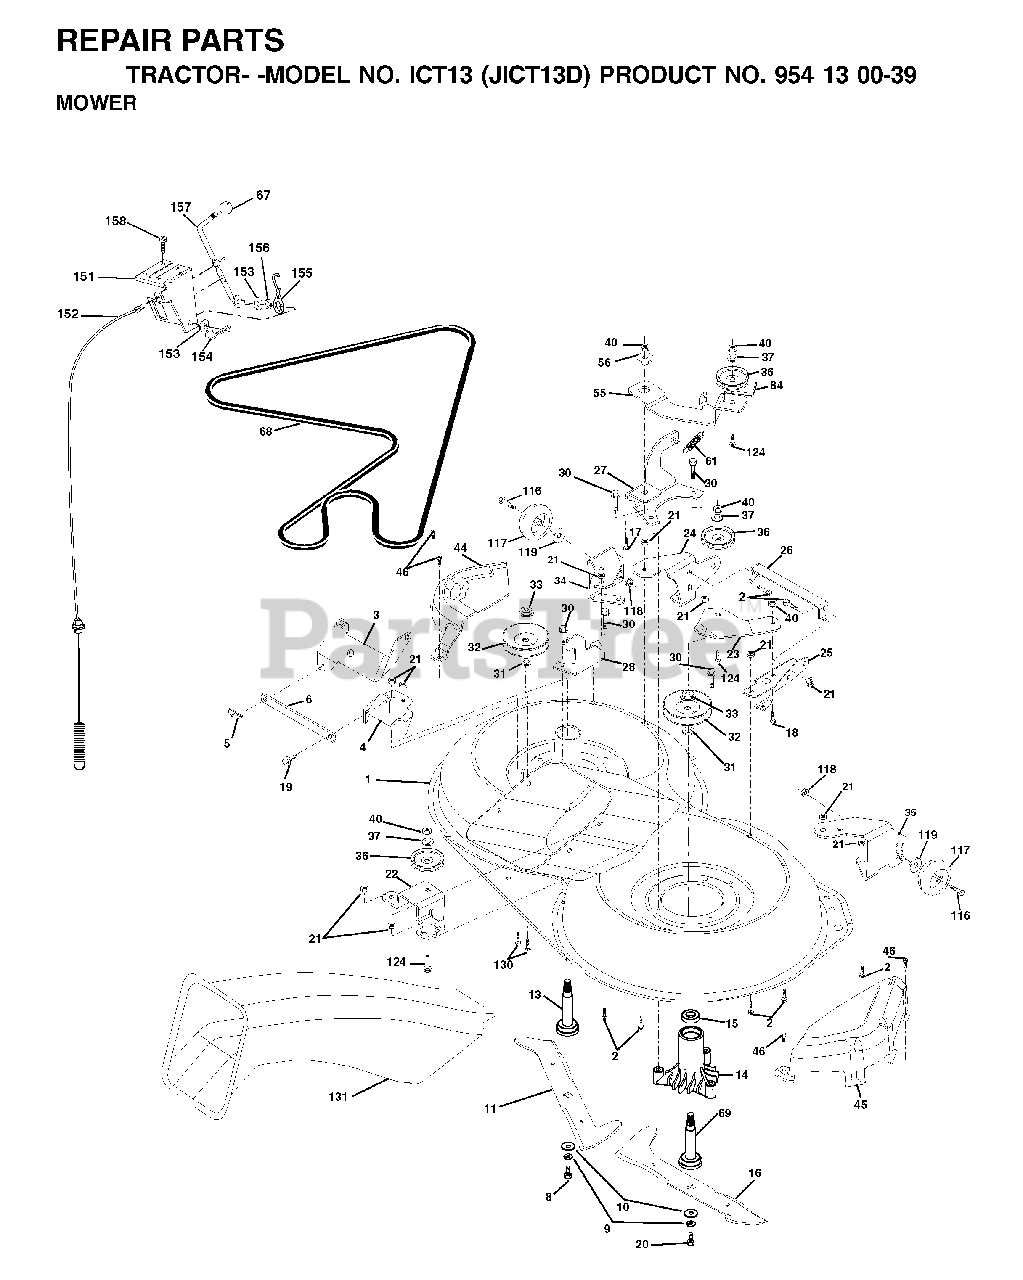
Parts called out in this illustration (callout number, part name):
1	MOWER HOUSING, DECK
2	BOLT
3	BRACKET
5	RETAINER-SPRNG RB
6	BAR SWAY
8	BLADE BOLT
9	LOCKWASHER
10	WASHER.BLADE
11	BLADE-LH 5PT STAR(CTH130)
12	BEARING
13	SHAFT ASM VENT
14	HSG MANDREL
16	BLADE RH 6PT STAR(CTH130)
17	BOLT.3/8-14X1.25
19	BOLT SHD 5/16-18
21	LOCKNUT
24	BRACKET
25	BRACKET
26	BRACE
28	BRACKET
30	SCREW THDROL ROLLING WASHER HD
31	WASHER
32	PULLEY, MANDREL
33	NUT
36	PULLEY.IDLER.4.25
40	LOCKNUT
45	COVER
46	SCREW.1/4-20X5/8
55	ARM IDLER
56	SPACER.RETAINER.MOWER
61	SPRING.TENSION.BELT
67	KNOB T (3/8 HOLE)
68	HEX-BELT 92 MOWER 105AA
69	SHAFT.ASM.W/LWR.BRG.RH.THREAD
84	KEEPER, BELT IDLER
116	BOLT, SHOULDER
117	WHEEL GAGE DONUT
118	LOCKNUT
119	WASHER
124	BOLT.3/8-16X1.50
128	WASHER FELT
131	CHUTE BAGGER
151	BRACKET, CLUTCH CABLE
153	WASHER FLAT 3/8"
154	SPRING RETAINER
155	SPRING RETENTION LEVER
156	SPACER CLUTCH CABLE
157	ROD CLUTCH CABLE 3/8"
158	SCREW LT
